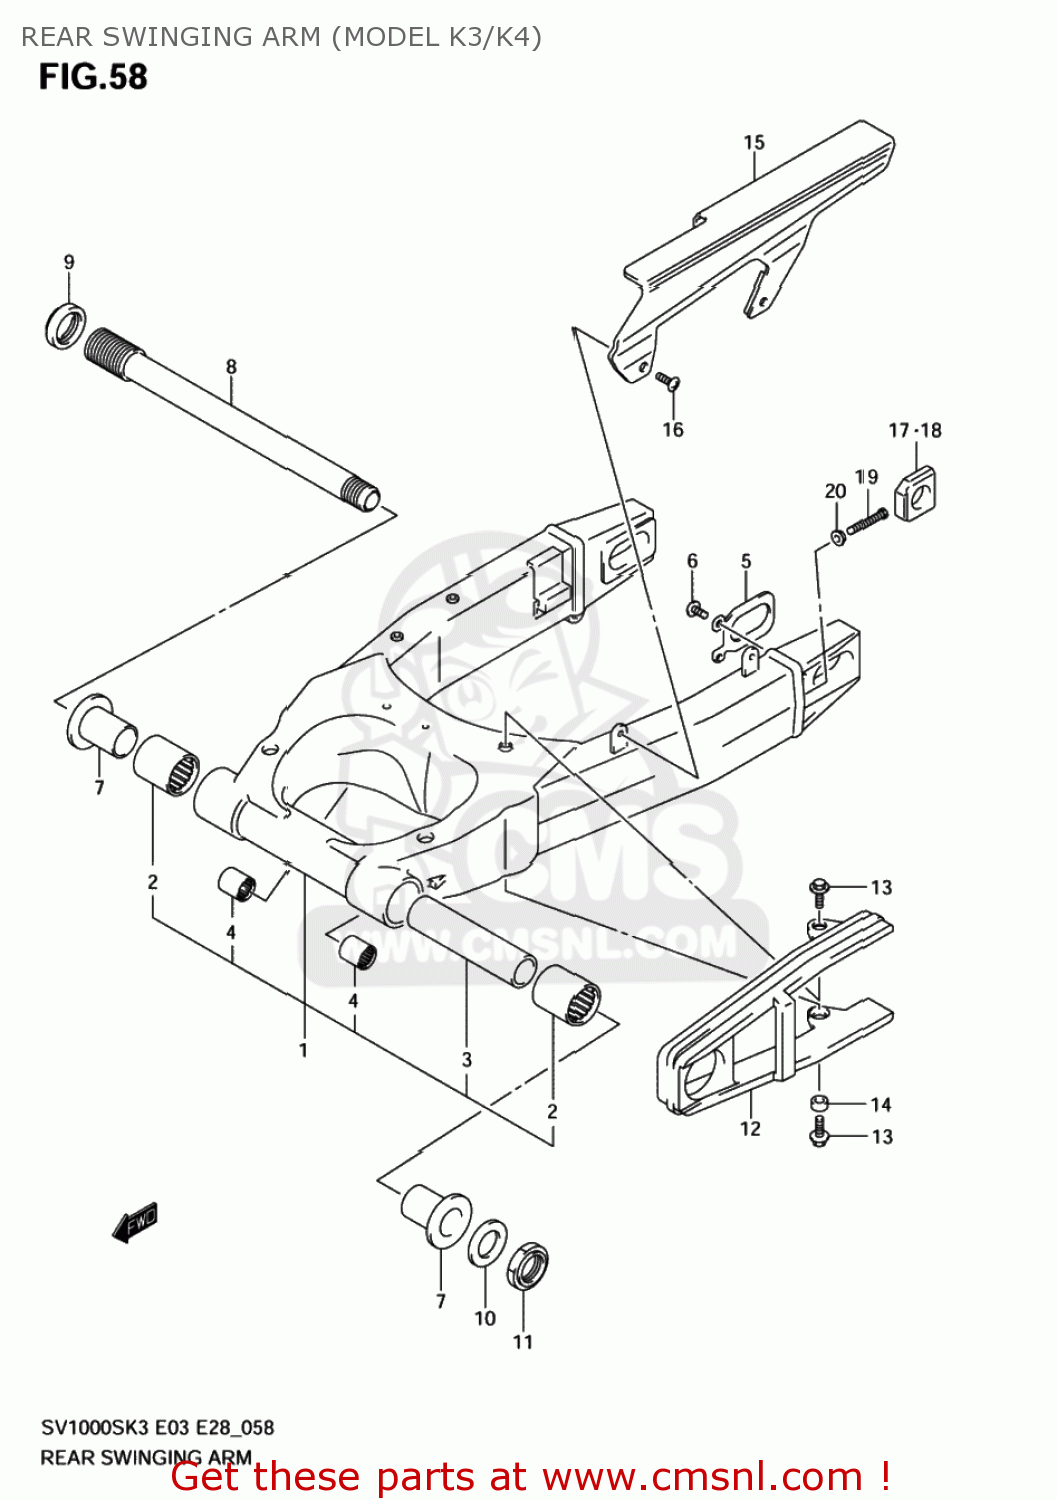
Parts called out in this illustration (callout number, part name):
1	SWINGINGARM ASSY,RR
2	BEARING(30X40X30)
3	SPACER,REAR SWING PIVOT,CENTER
4	BEARING(17X24X20)
5	PLATE,RR SWING ARM BRKT
6	SCREW
7	SPACER,RR SWGARM PIVOT BEARING
8	SHAFT,RR SWINGINGARM PIVOT
9	NUT,RR SWGARM PIVOT BOLT
10	WASHER(25.2X42X3.2)
11	NUT
12	BUFFER,CHAIN TOUCH DEFENSE
13	BOLT(6X20)
14	SPACER(6.5X12X5.5)
15	CASE,CHAIN
16	BOLT(6X16)
17	ADJUSTER,CHAIN,R
18	ADJUSTER,CHAIN,L
19	BOLT(8X50)
20	NUT
